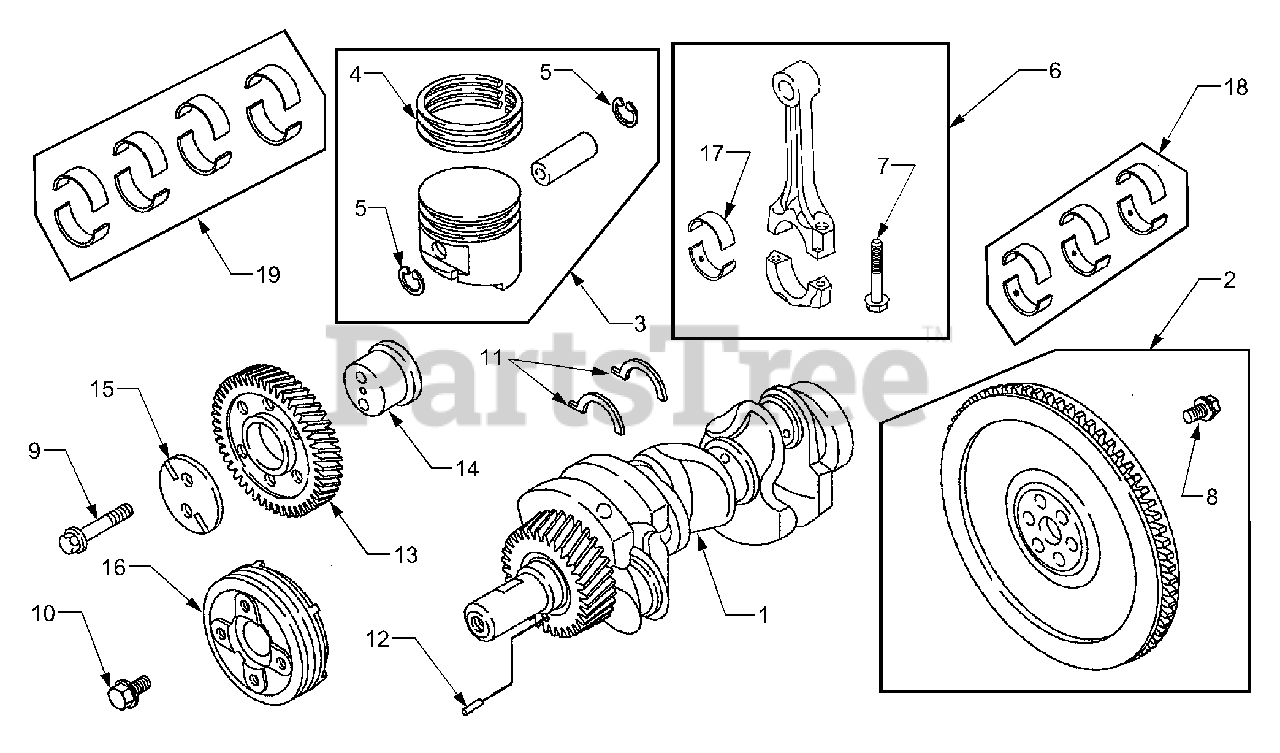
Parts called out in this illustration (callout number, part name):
1	Crankshaft
3	Piston Assembly, Standard
4	Ring Set, Standard
5	Lock Ring, Piston Pin
6	Rod, Connecting
7	Screw, Connecting Rod
8	Screw, Hex, 10mm
9	Screw, Hex, 8mm
10	Screw, Hex
11	Washer, Thrust, Standard
12	Pin, Locating
13	Gear, Drive
14	Shaft, Gear
15	Plate, Idler Gear
16	Pulley, Crankshaft
17	Bearing, Rod Standard
18	Bearing Set, Rod Standard
19	Bearing Set, Main Standard
